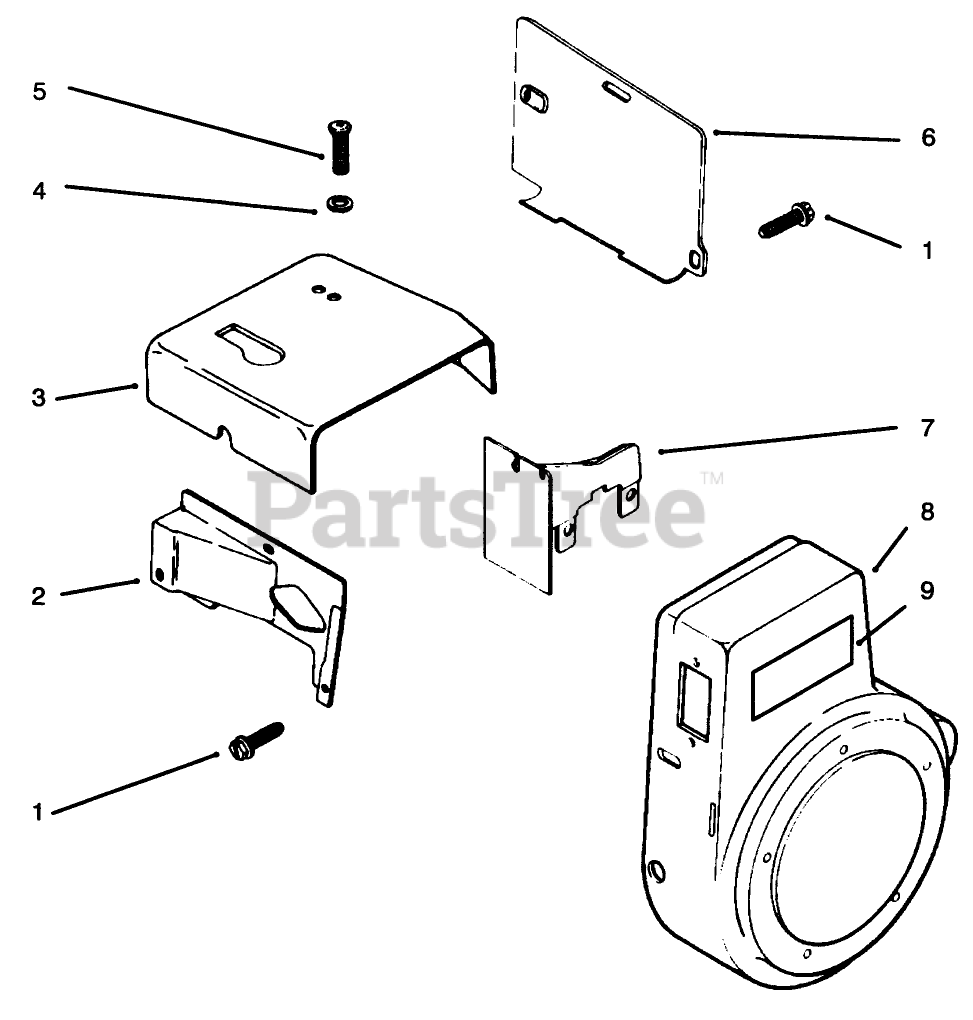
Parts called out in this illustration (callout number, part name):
1	Screw-Hex Hd
2	Baffle-Side Air
3	Baffle-Head
4	Washer
5	Screw, F.H.
6	Baffle-Cylinder
7	Baffle-Inner
8	Housing-Blower
